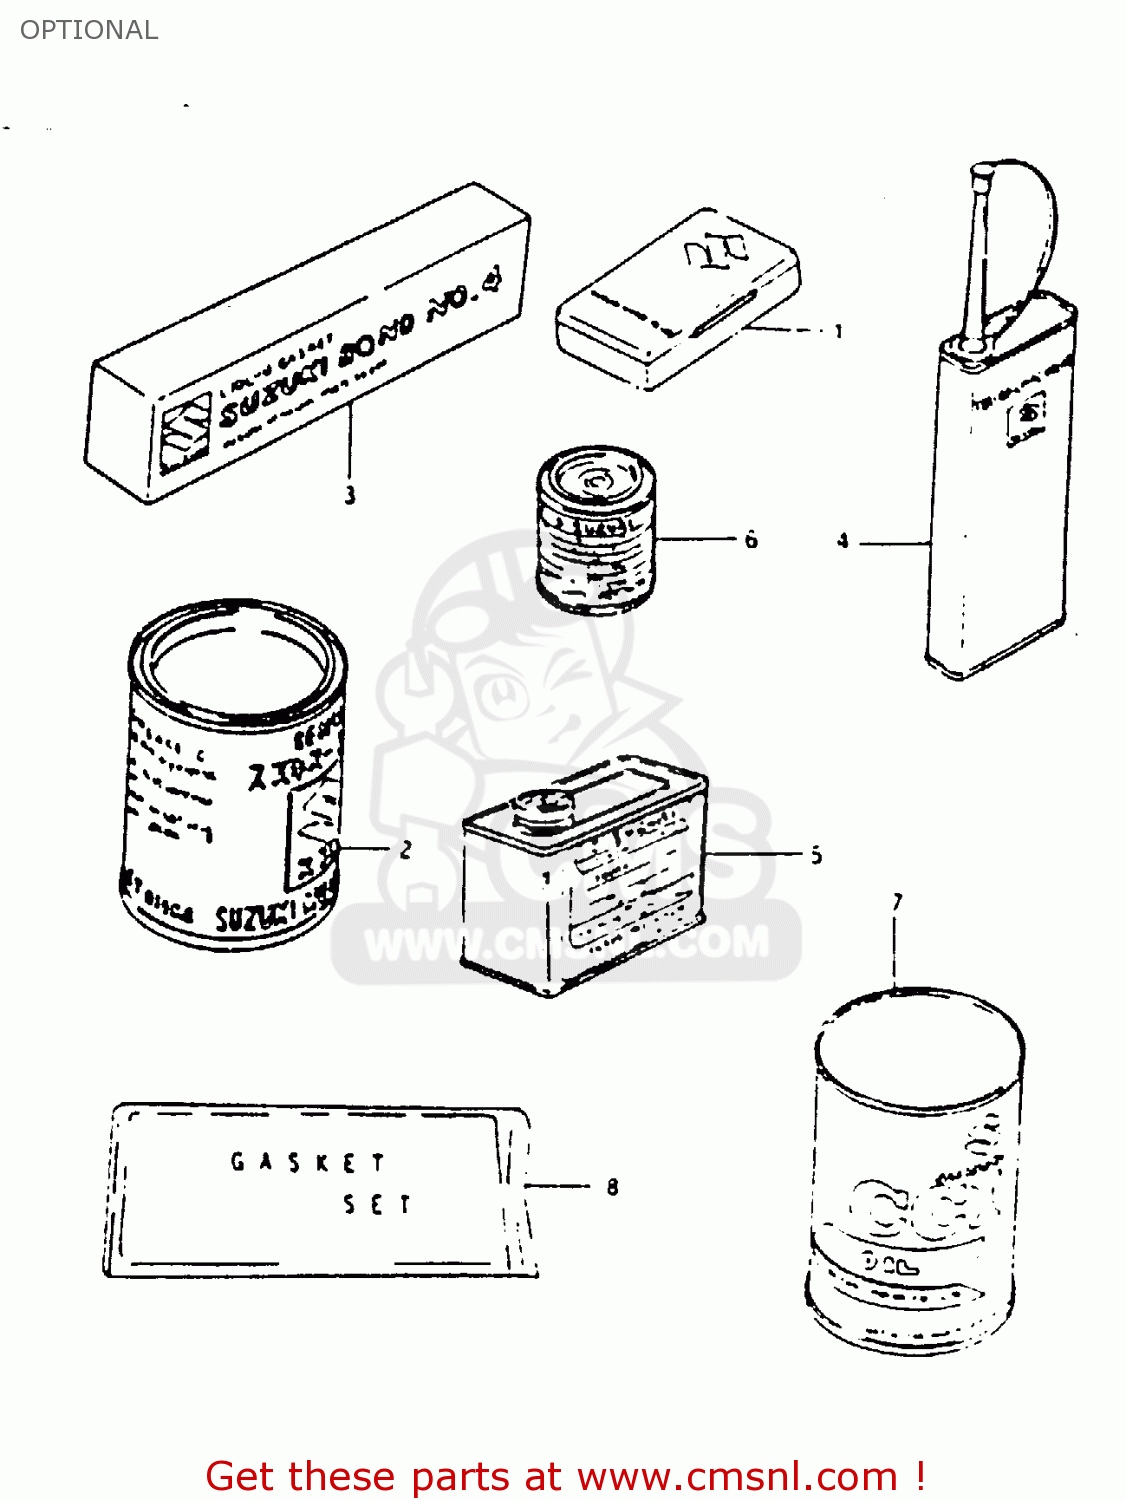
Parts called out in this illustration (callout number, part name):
1	TUBE REPARING TOOL
2	GREASE(C)EP2 LITHIUM 150G
3	BOND 1104
4	THREAD LOCK NO.1401 CLEAR 200G
5	PAINT (BLACK)
6	PAINT,BLACK
7	CCI OIL
8	GASKET SET (MCA)
